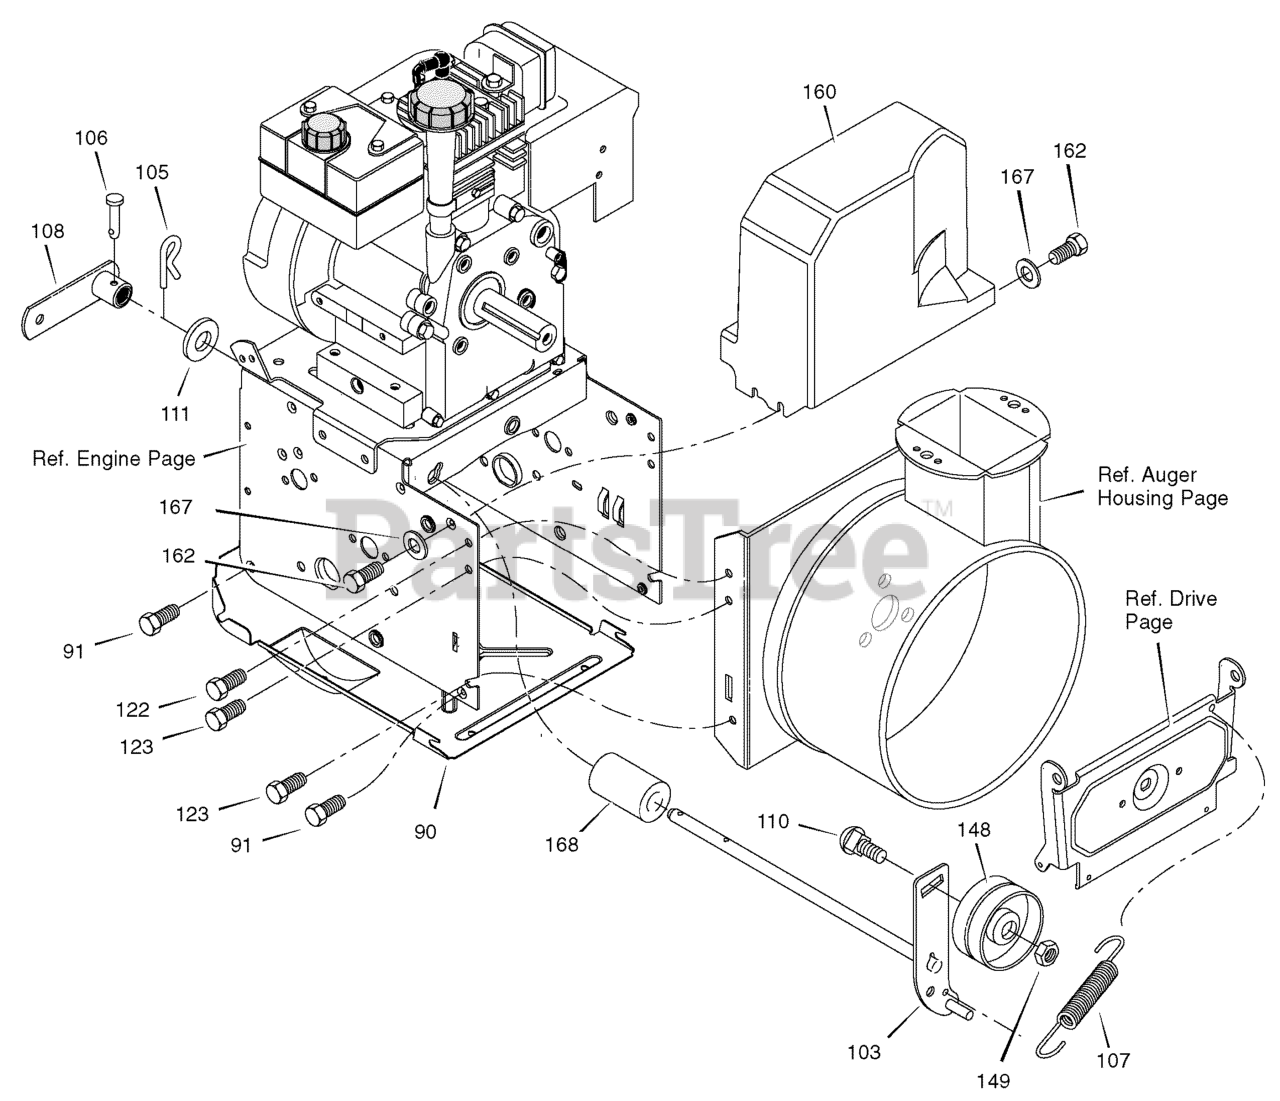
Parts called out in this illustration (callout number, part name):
90	COVER, BOTTOM
91	SCREW, 1/4-20X .63
103	IDLER ASSEMBLY, AUGER
105	PIN, HAIR .38DIAX1.64LG
106	PIN, CLEVIS 3/16" DIA
107	SPRING, TENSION
108	ASSY., SPRING ATTACH
110	BOLT, 3/8-16X1.25 CARR.
111	WASHER, FLAT
122	SCREW, TAP 5/16-18 X .75
123	SCREW, TAP 5/16-18 X .50
148	PULLEY, IDLER
149	NUT, JAM 3/8-16
160	COVER, BELT
162	SCREW, TAP
166	WASHER, FLAT
168	SPACER, AUGER BRACKET
